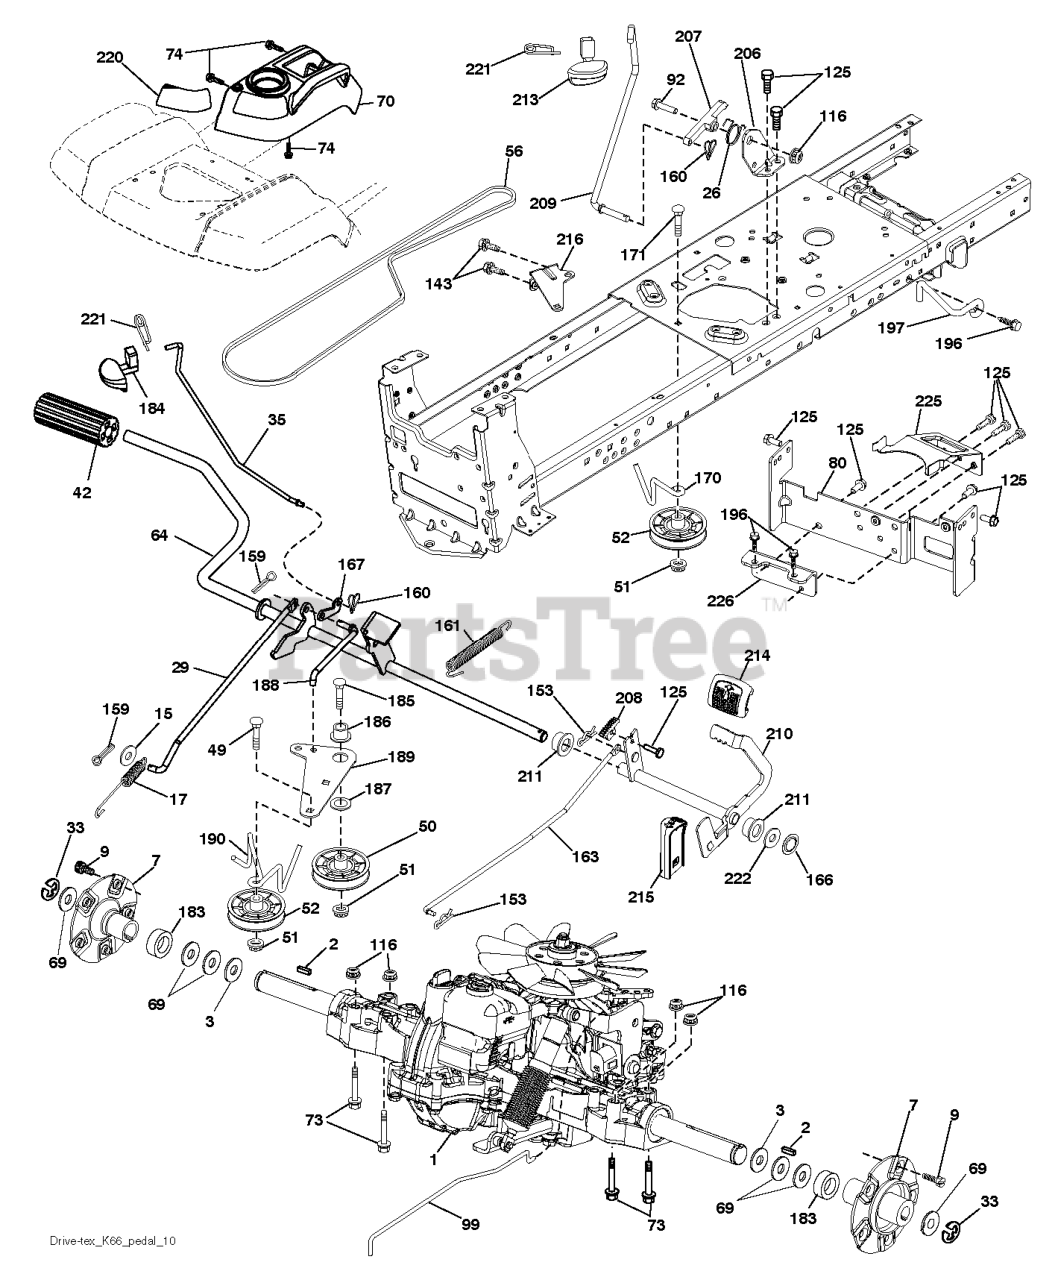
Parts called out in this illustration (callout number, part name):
2	KEY 1/4 X 2.5
7	HUB.ASM.WHEEL.REAR.23"TEX
9	HUB BOLT
15	WASHER
17	SPRING.BRAKE.K46
26	SPRING.RETURN.CRUISE
29	ROD.BRAKE.K66
33	E RING HYT
35	ROD.BRAKE.PARTK.HUSQ.TEX
42	PEDAL COVER T
50	IDLER.FLAT.910.OFFSET
51	NUT LOCK FLG 3/8-16 UNC
52	IDLER.V-GROOVE.910.OFFSET
64	SHAFT.ASM.PEDAL.BRK.CNTR
70	CONSOLE.ASM.RH.GT.FC.HUSQ
73	BOLT HEX 5/16-18 GR 5
74	SCREW.HI-LO.CONSOLE
80	STRAP.TORQUE.K66
92	BOLT
99	ROD.SPRING.BYPASS.K66.GT.Z
116	NUT LOCK HEX FLANGE 5/16-18
125	SCREW
143	SCREW LT
153	RETAINER M
159	COTTER PIN
160	RETAINER CLIP
161	SPRING, RETURN LT
163	ROD.PEDAL.CONTROL
166	NUT.PUSH.625
167	LATCH.BRAKE.SPRING
170	KEEPER.V-IDLER.CENTER.
171	BOLT
183	SPACER.AXLE.HG.TEX
184	RB HANDLE.PARKG.BRK.HUS/PRED
186	SPACER.RETAINER
187	WASHER 12/32X2X10GA
188	RP.LINK.CLUTCH.GROUND.DRIVE
189	BELLCRANK.GROUND.DRIVE.TEX.
190	KEEPER.BELLCRANK.DRIVE
196	SCREW 3/8-16X1
197	BRKT.ANIT-ROTATION.CLUTCH
206	BRKT.MOUNT.LATCH.CRUIS
207	LATCH.CONTROL.CRUISE
208	GEAR.SECTOR.CONTROL.CR
209	ROD.CONTROL.CRUISE.GT.
210	ROCKER.ASM.PEDAL.CONTR
211	BEARING.NYLON
213	KNOB.CONTROL.CRUSIE.HU
214	PEDAL.FORWARD.PAD.TEX
215	PEDAL.REVERSE.TEX.GT.4
216	BRACKET.PULLEY.IDLER.W/TEX
220	REFLECTOR.RH.TEX GT
221	RETAINER.SPRING.CLIP.H
222	WASHER 21/32 X 1-1/4 X 10 GA.
225	KEEPER.BELT.TRANSAXLE.K66
226	BRACKET.MOUNT.TORQUE.K66.TG
